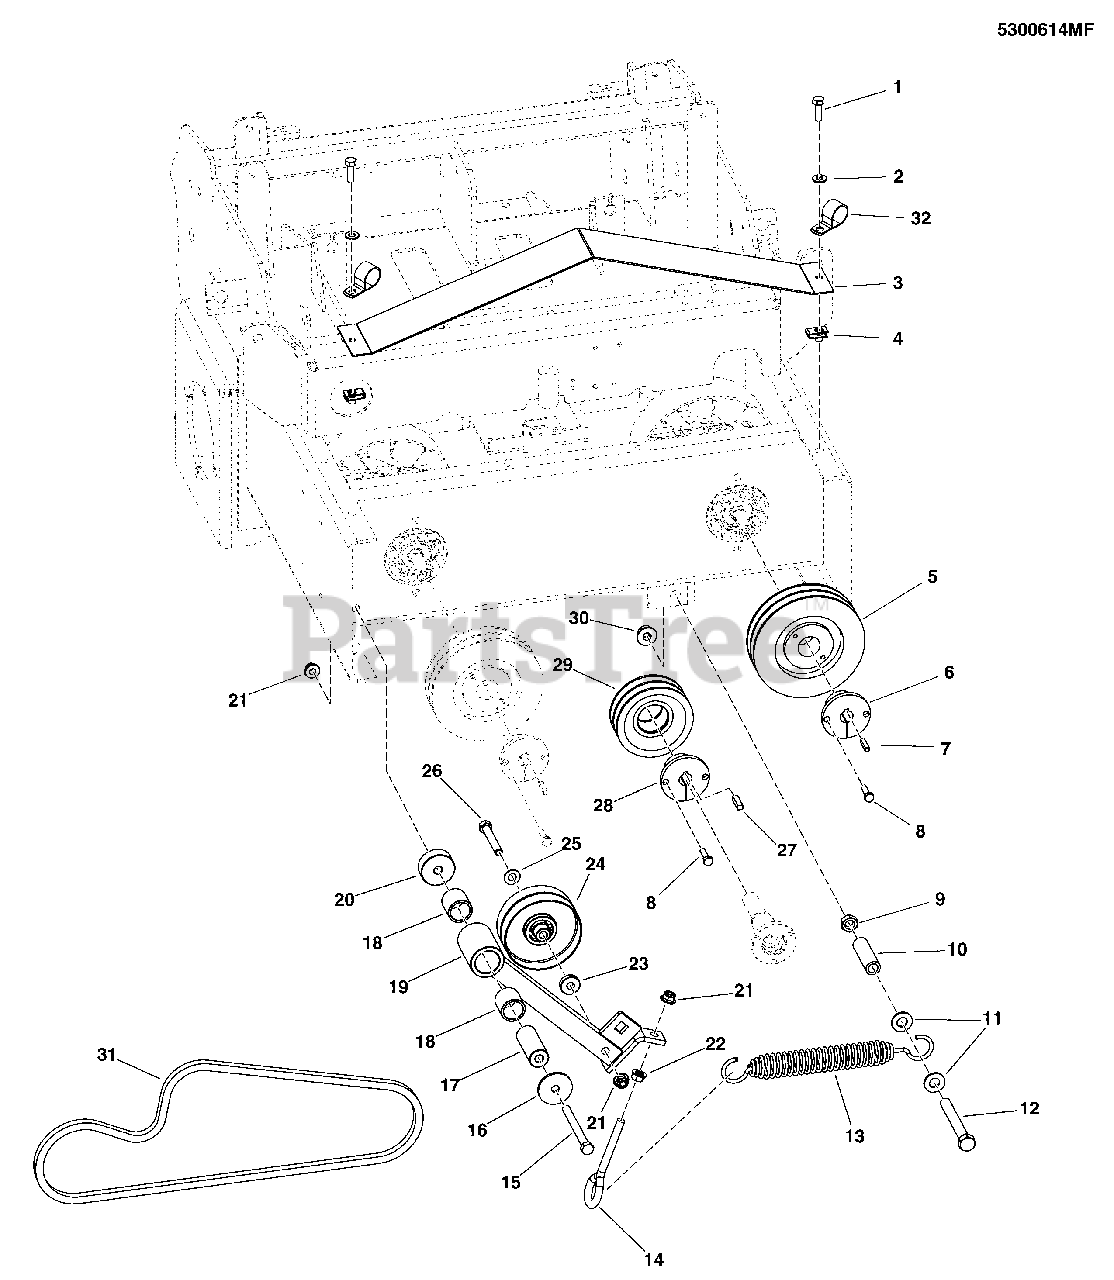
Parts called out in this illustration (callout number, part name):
1	BOLT, 5/16-18 X 1 GD5 YZ
2	WASHER, 5/16 SAE
3	GUARD, OUTFRONT BELT, PERFORATED
4	BODY CLIP, 5/16-18-7GA MATERIAL
5	PULLEY 5.00 OD, DOUBLE "A" GROOVE
6	BUSHING, 17MM, HQ
7	KEY, 5MM SQ. W/RADIUS
8	BOLT, 1/4-20 X 1", GD
9	NUT, 1/2-13 HEX JAM
10	HOSE, 1/2" PUSH-ON 2.25"
11	WASHER, 1/2 SAE
12	BOLT, 1/2-13 X 4 GD5 YZ
13	SPRING, EXTENSION, SWIVEL, SHORT HOOK
14	EYE BOLT, 3/8-16 X 5, 1 EYE
15	BOLT, 3/8-16 X 4 GD5 YZ
16	WASHER, .41 X 1.75 X .14
17	SPACER, .39 X 1.00 X 2.55, SS
18	SPACER, .39 X 1.00 X 2.55
19	WELD, ARM, PUMP DRIVE IDLER - RED
20	SPACER, .39 X 1.75 X .63, YZ
21	NUT, 3/8-16 HEX NYLOCK FLANGE
22	NUT, 3/8-16 HEX SERRATED FLANGE
23	SPACER, .39 X 1.00 X .25
24	PULLEY, FLAT IDLER 4
25	WASHER, 3/8 SAE
26	BOLT, 3/8-16 X 2-1/2 GD5 YZ
27	KEY, 1/4 SQ. X 1.00
28	TAPER LOCK BUSHING, HQ-1-1/8"
29	PULLEY, 4.25 OD X 2 GROOVE, DH2425
30	NUT, 1/2-13 HEX NYLOCK FLANGE
31	BELT, 55.6 EL, MATCHED SET, A-SEC
32	CLAMP, HOSE, 1.00 DIA.
